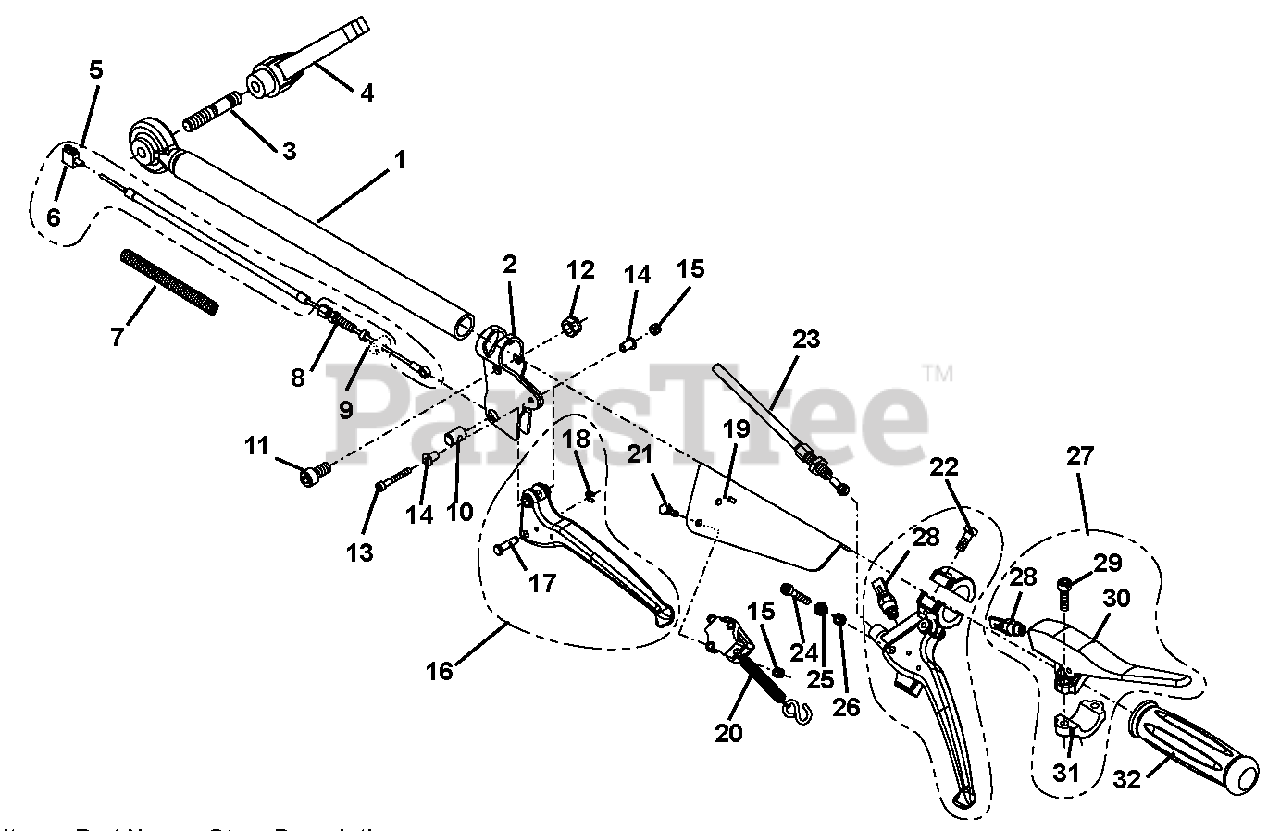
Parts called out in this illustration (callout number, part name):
1	Handlebar Extension
2	Guide, Lever
3	Threaded Bolt, D939 M10FO x 45
4	Clamping Lever, L= 80 M10 x 20
5	Cable Pull, INKL. (Includes item 5)
6	Nipple, 2 MM
7	Spring Tension
8	Set Collar, M6 x 36
9	Distance Ring
10	Shaft, Stay
11	Screw, D912 Metric 8 x 16
12	Nut, Lock, D985 Metric 8
13	Screw, D912 Metric 4 x 30
15	Nut, Lock, D985 Metric 4
16	Hand Lever, (Includes items 17 - 18)
18	Washer, Lock
21	Hex Bolt, D933 Metric 4 x 16
22	Lever Assembly (Includes item 28)
23	Assembly, Cable
24	Screw, Cylindrical Head
26	Nut, Lock
27	Dead Mans Lever Assembly
30	Lever, Emergency
32	Rubber, Handle
